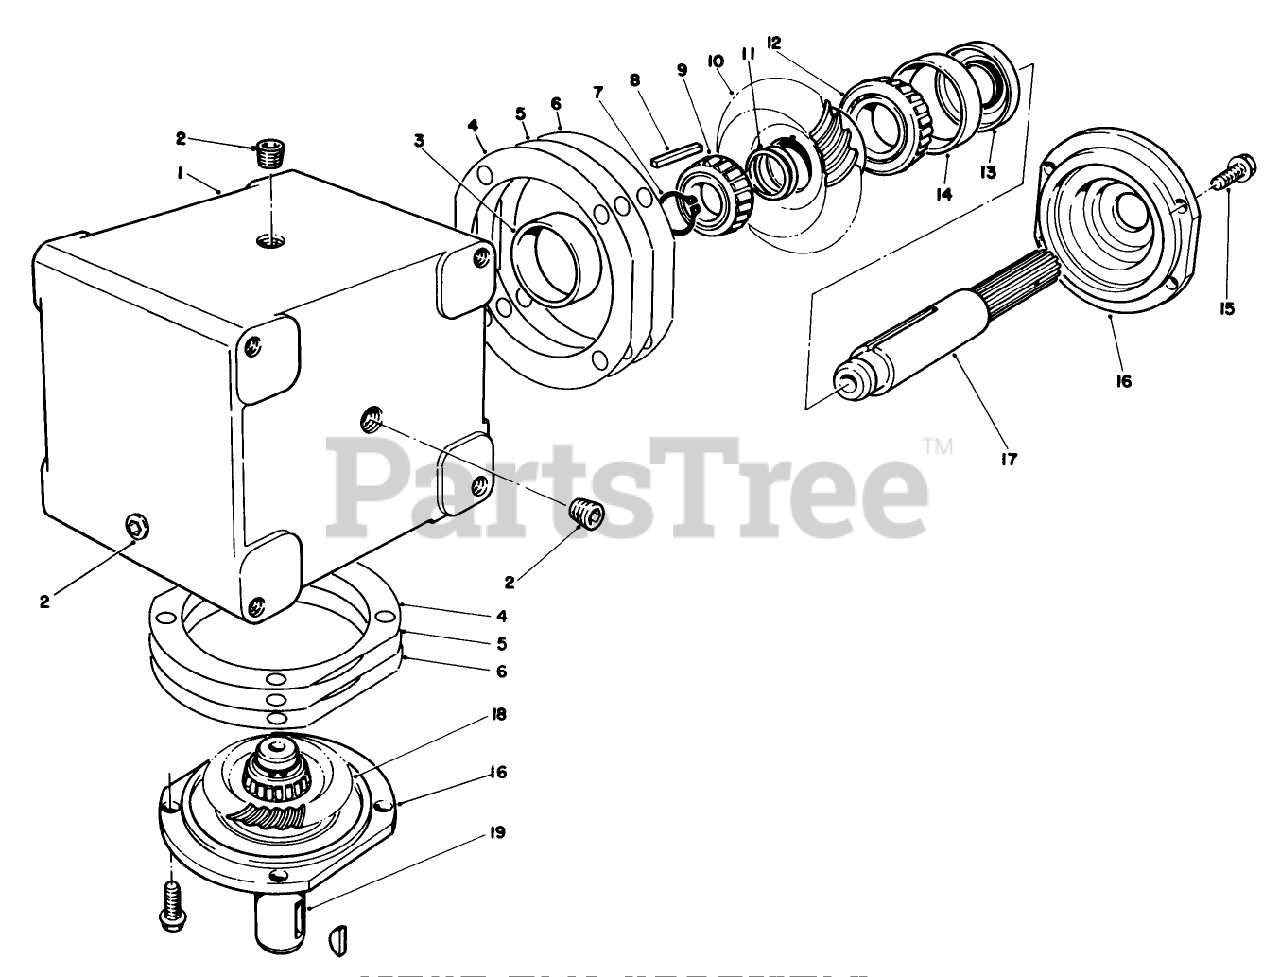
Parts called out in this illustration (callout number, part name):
4	GASKET
5	GASKET
10	SEE SB GEN#14-01
17	SEE SB GEN 14-01
18	SEE SB GEN#14-01
19	SEE SB GEN#14-01
